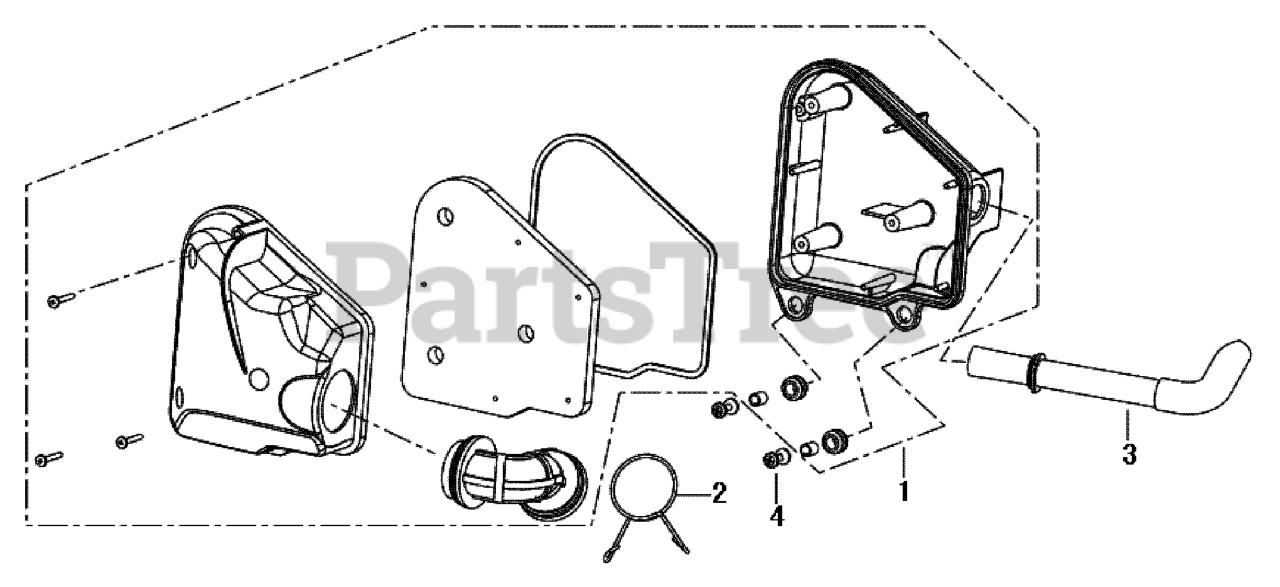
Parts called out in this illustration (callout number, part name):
1	AIR CLEANER ASSY.
2	CLIP, SPRING
4	SCREW-WASHER ASSY.
